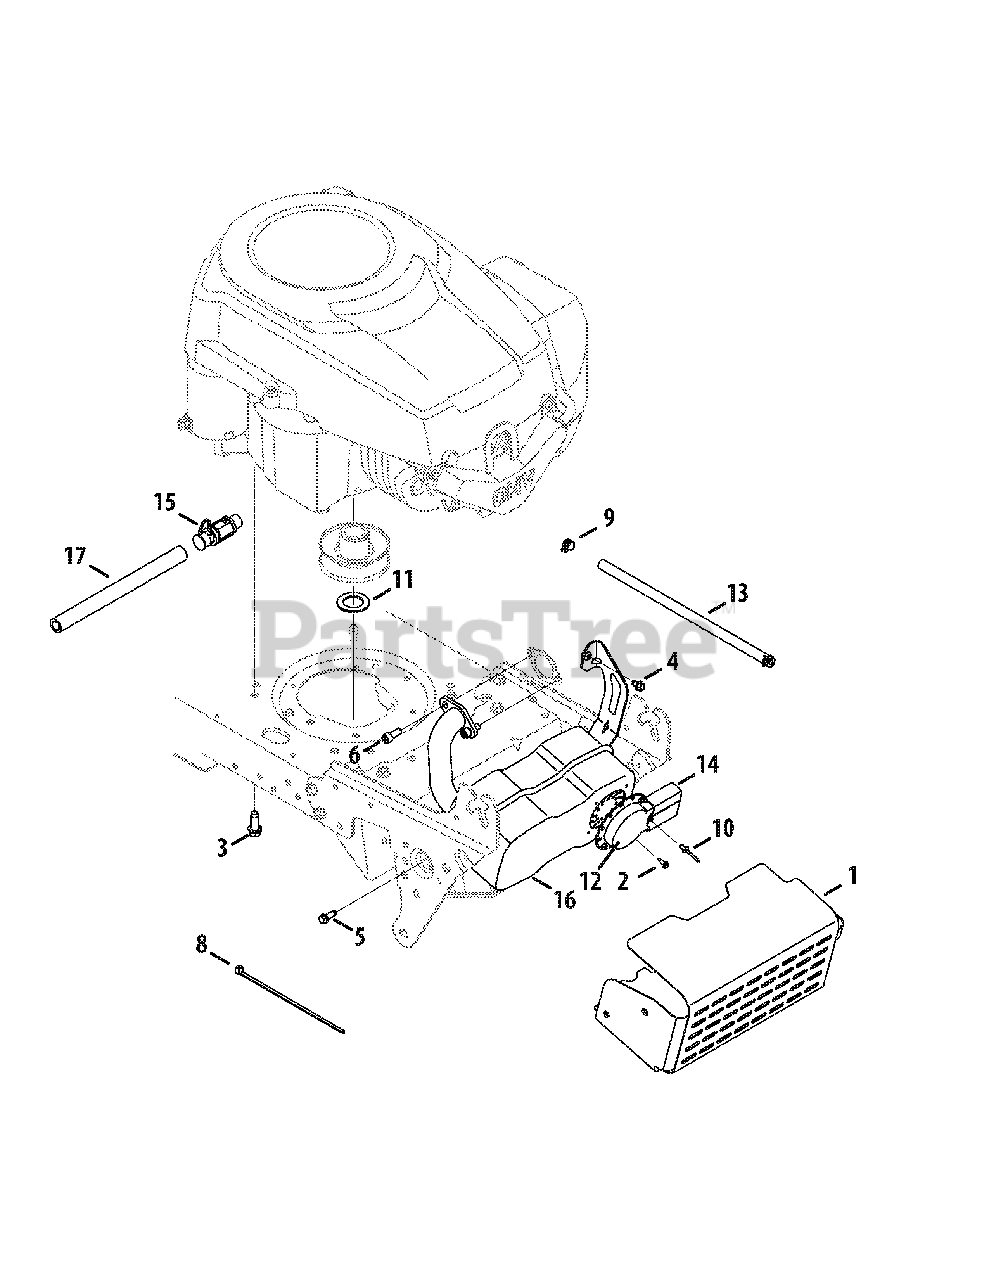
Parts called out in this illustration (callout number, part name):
1	Muffler Shield Assembly
2	Screw, #8-18 x .50
3	Self-tapping Screw, 3/8-16, 1.00
4	Screw, 1/4-20, 0.500
5	Self-tapping Screw, 1/4-20, .750
6	Socket Cap Screw, 5/16-18, .625
8	Cable Tie, 7.4"
9	Hose Clamp, .490
10	Pop Rivet, .188 x .300
11	Flat Washer, 1.031 x 1.620 x .095
12	Muffler Deflector
13	Fuel Line Hose
14	Muffler Deflector, Long
15	Oil Drain
16	Muffler
17	Oil Drain Extension Hose
